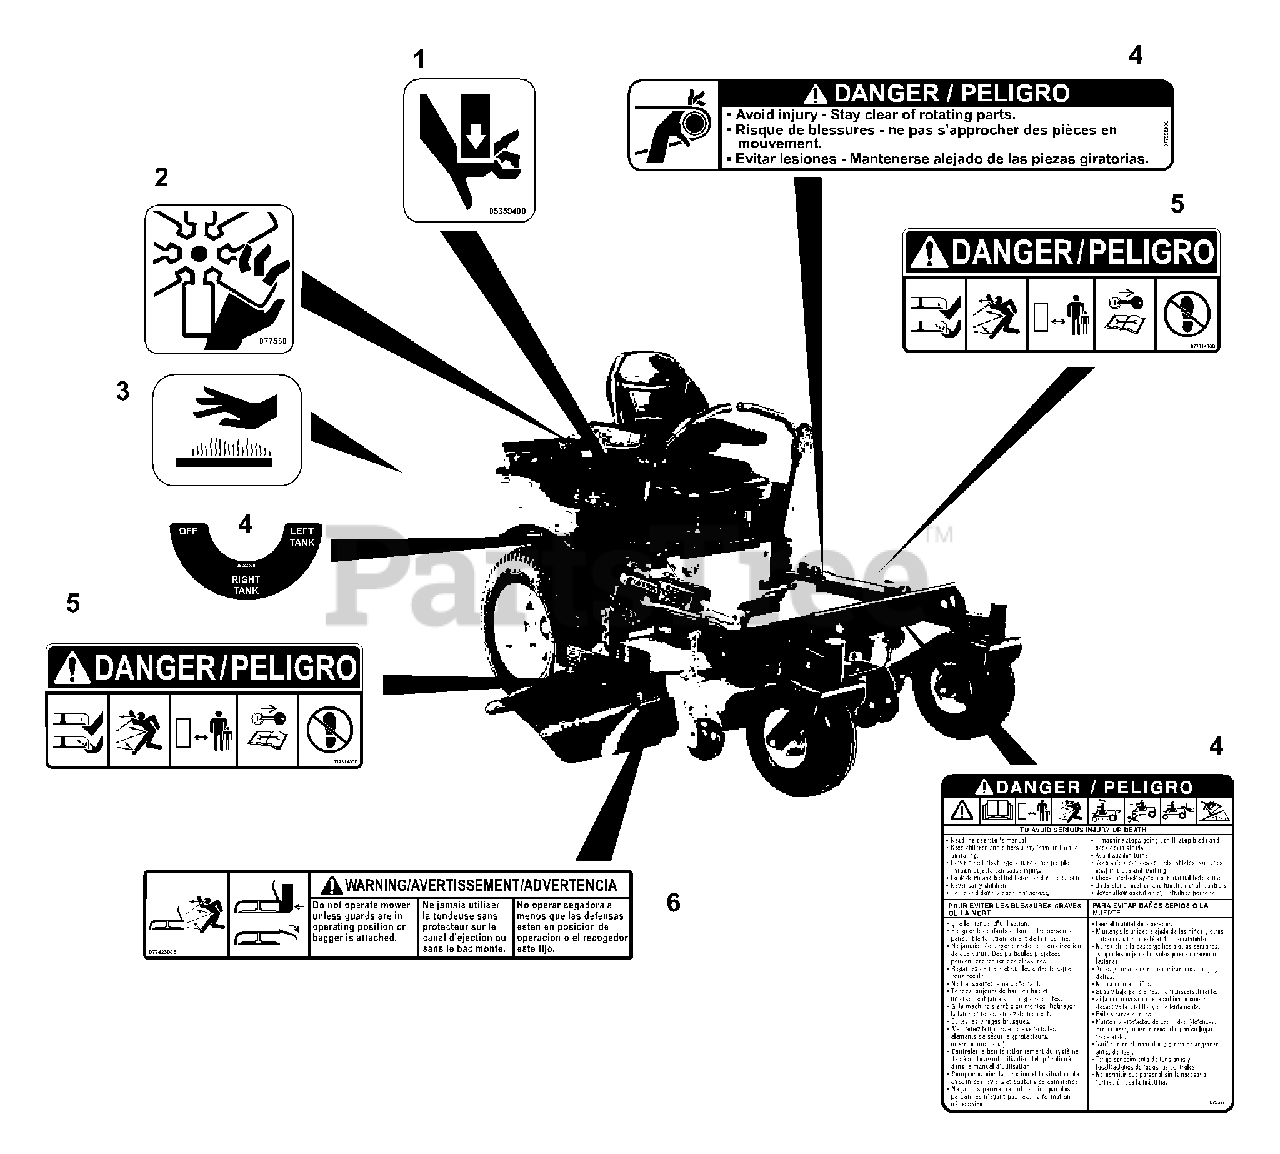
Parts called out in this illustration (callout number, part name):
1	Decal, Pinch Point
2	Decal, Danger Fan
3	Decal, Hot Surface
4	Set, Decal-Common Danger/Fuel
5	Decal, Mower Pan Head Danger
6	Decal, Warning
